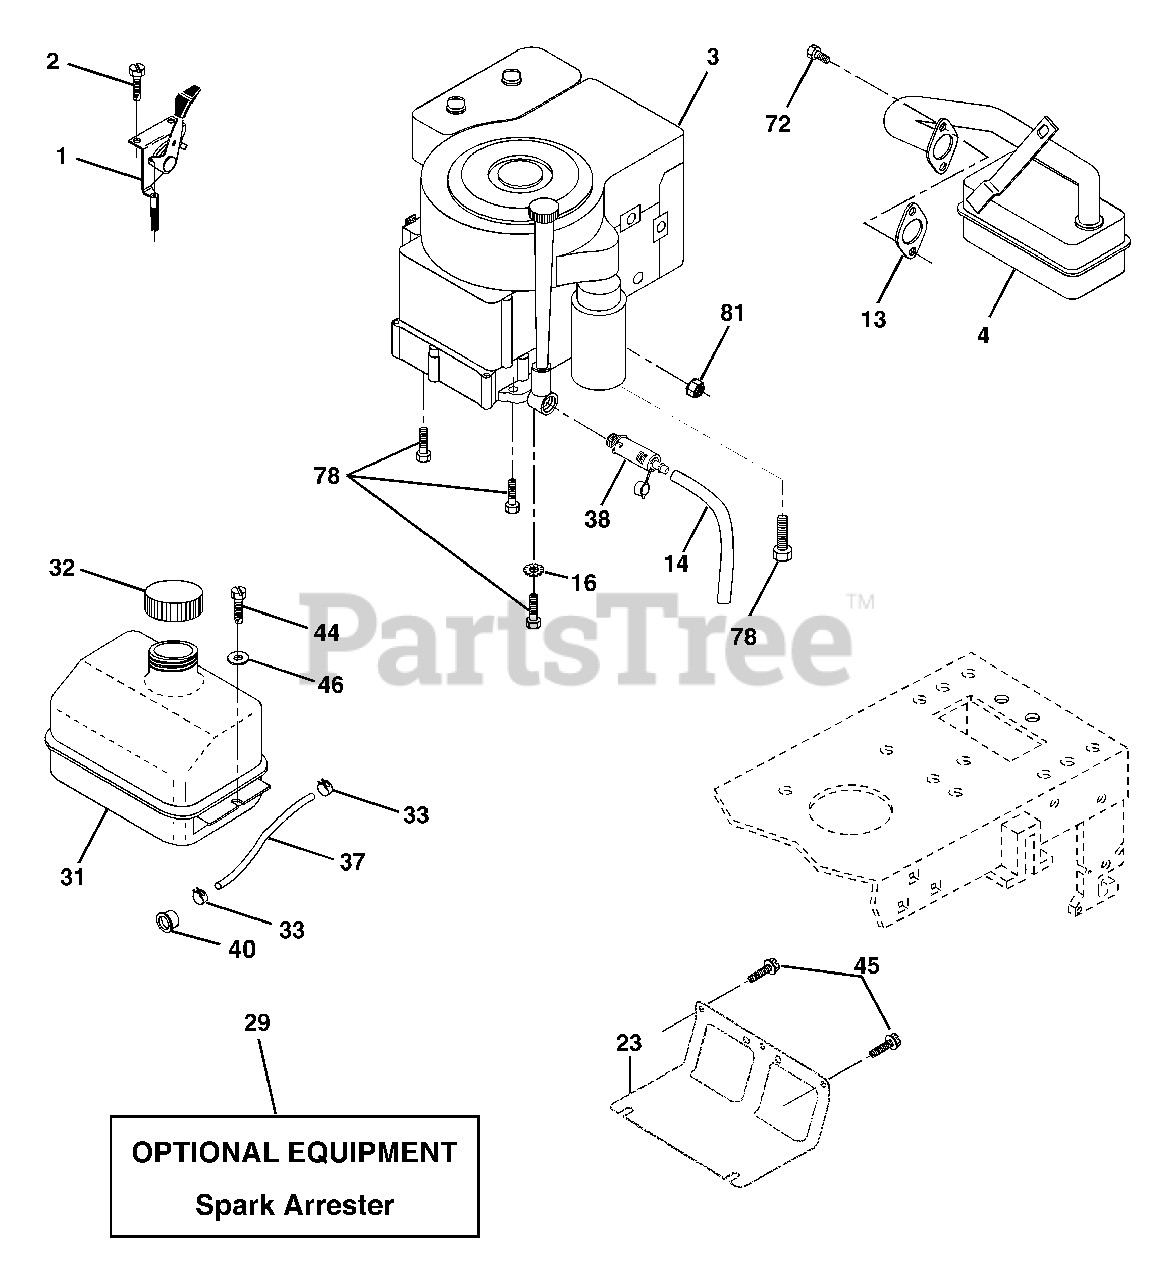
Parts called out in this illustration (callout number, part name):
1	Control Th/ch Flag
2	Screw Hex Thd Cut 1/4-20 x 1/2
4	Muffler Exhaust
13	Gasket Eng 1 313 Id Tin Plated
14	Tube Drain Oil Easy
16	Washer Lock Ext Tooth 3/8
23	Shield BRN/DBR Guard
29	Kit Spark Arrestor (Flat Scrn)
31	Tank Fuel Front
32	Cap Asm Fuel
33	Clamp Hose
37	Line Fuel 20"
38	Plug Drain Oil Easy
40	Bushing Snap Nyl Blk Fuel Line
44	Screw Thdrol 1/4-20 x 3/4
45	Screw Hex Wsh Thdrol 3/8-16
46	Washer 9/32 X 7/8 X 16 Ga
72	Screw Socket Head 5/16-18 x 1
78	Screw 3/8-16 x 1-1/4
81	Nut Keps Hex 1/4-20 Unc
